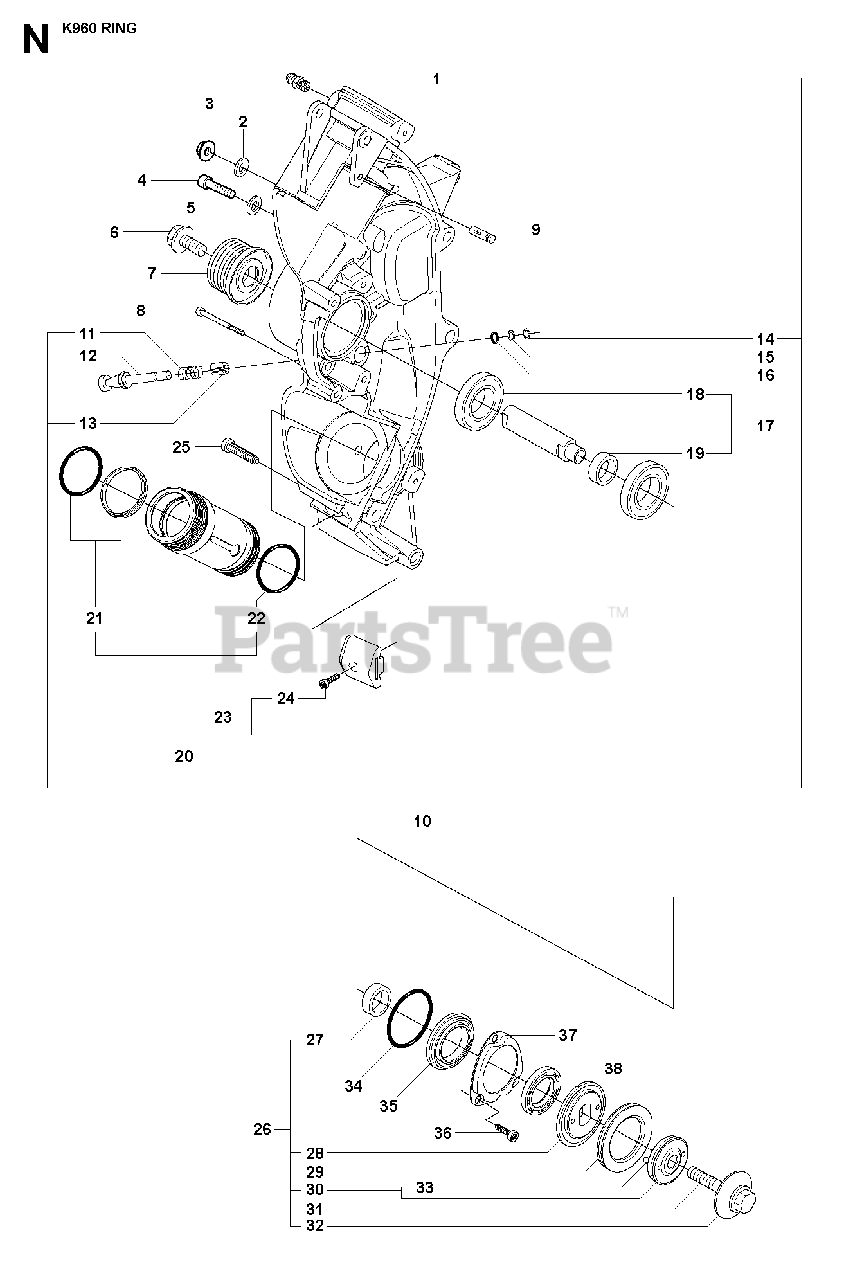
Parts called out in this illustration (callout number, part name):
1	LUBRICATION NIPPLE
8	SCREW ITXSCM
10	CHASSISIncl. 1, 9, 11 - 17, 20
17	DRIVE SHAFTIncl. 18 - 19
18	BALL BEARING
20	SLEEVEIncl. 21 - 22
23	WEAR PROTECTIONIncl. 24
25	SCREW ITXSCM
26	GEAR WHEEL ASSYIncl. 27 - 32
36	SCREW ITXSCM
38	SEALING RING
